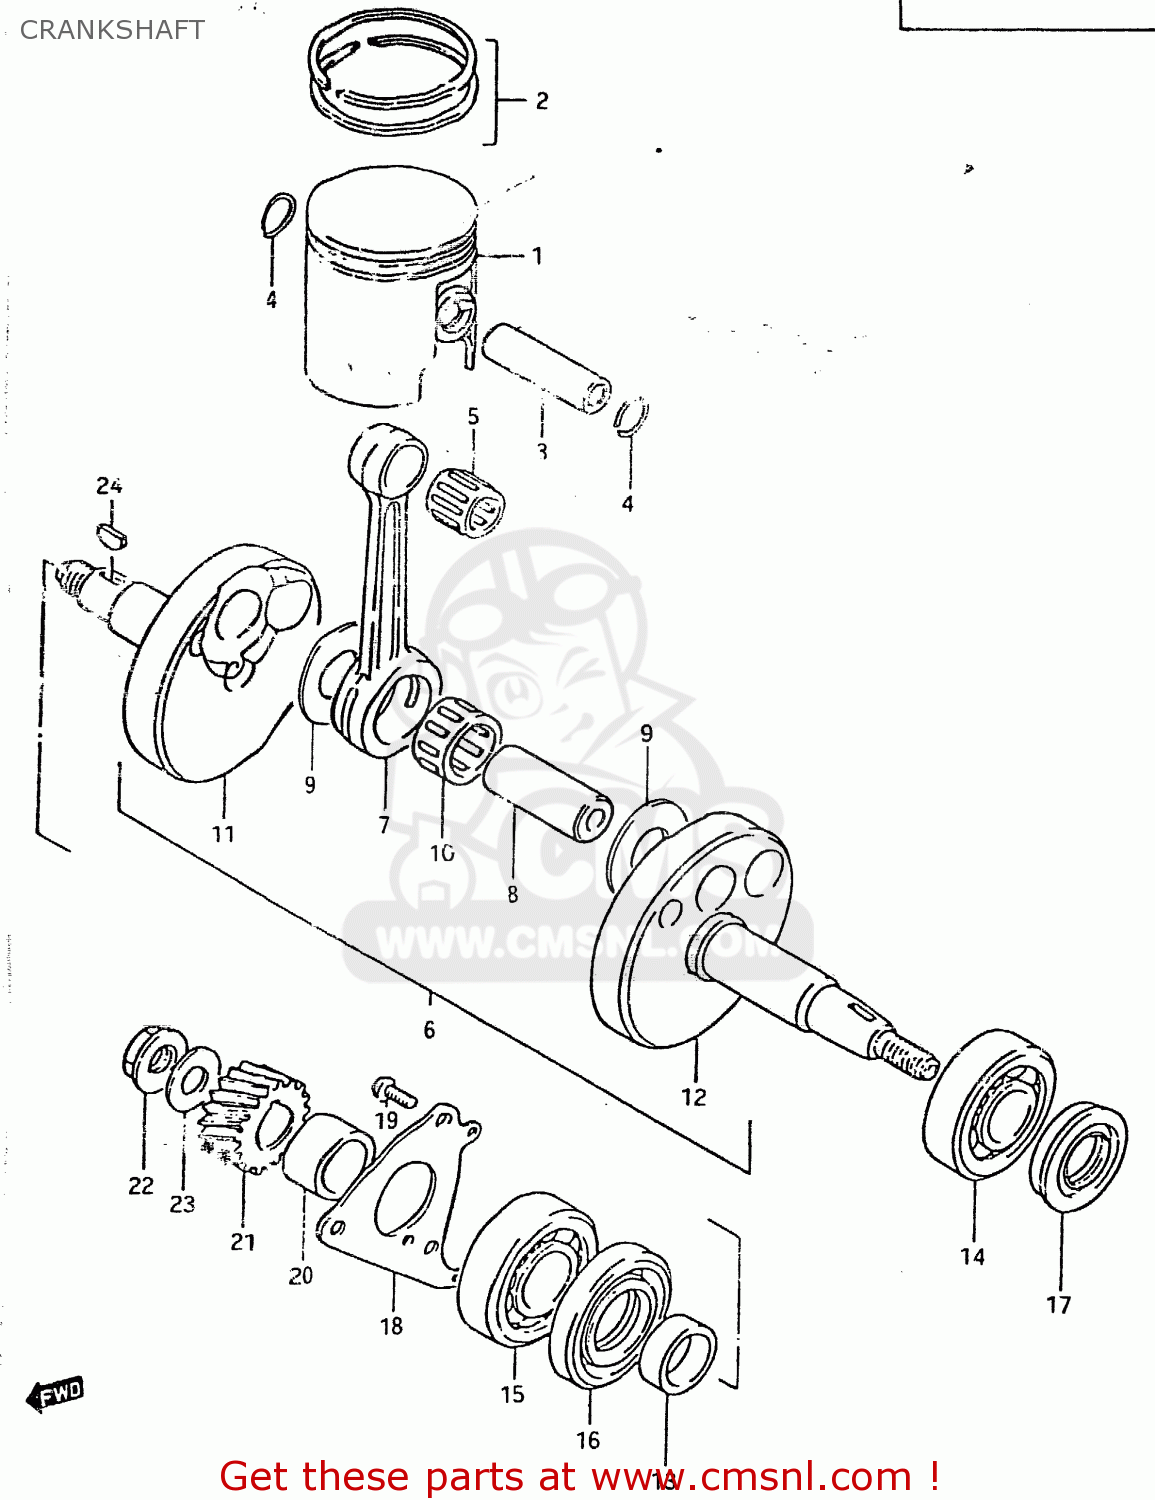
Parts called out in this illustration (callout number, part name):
1	PISTON
2	RING SET,PISTON
3	PIN,PISTON
4	RING,SNAP
5	BEARING
6	CRANKSHAFT ASSY
7	CONNECTING ROD
8	PIN,CRANK
9	WASHER(16X29X1)
10	BEARING
11	CRANKSHAFT
12	CRANKSHAFT, LH
13	SPACER(20X26X9)
14	BEARING(20X47X14)
15	BEARING
16	SEAL,OIL(26X47X7.3)
17	SEAL,OIL(19.6X37X8)
18	RETAINER,CRANKSHAFT BEARING,R
19	SCREW 6X12
20	SPACER(20X26X14)
21	GEAR,PRIMARY DRIVE NO.19
22	NUT
23	WASHER
24	KEY
